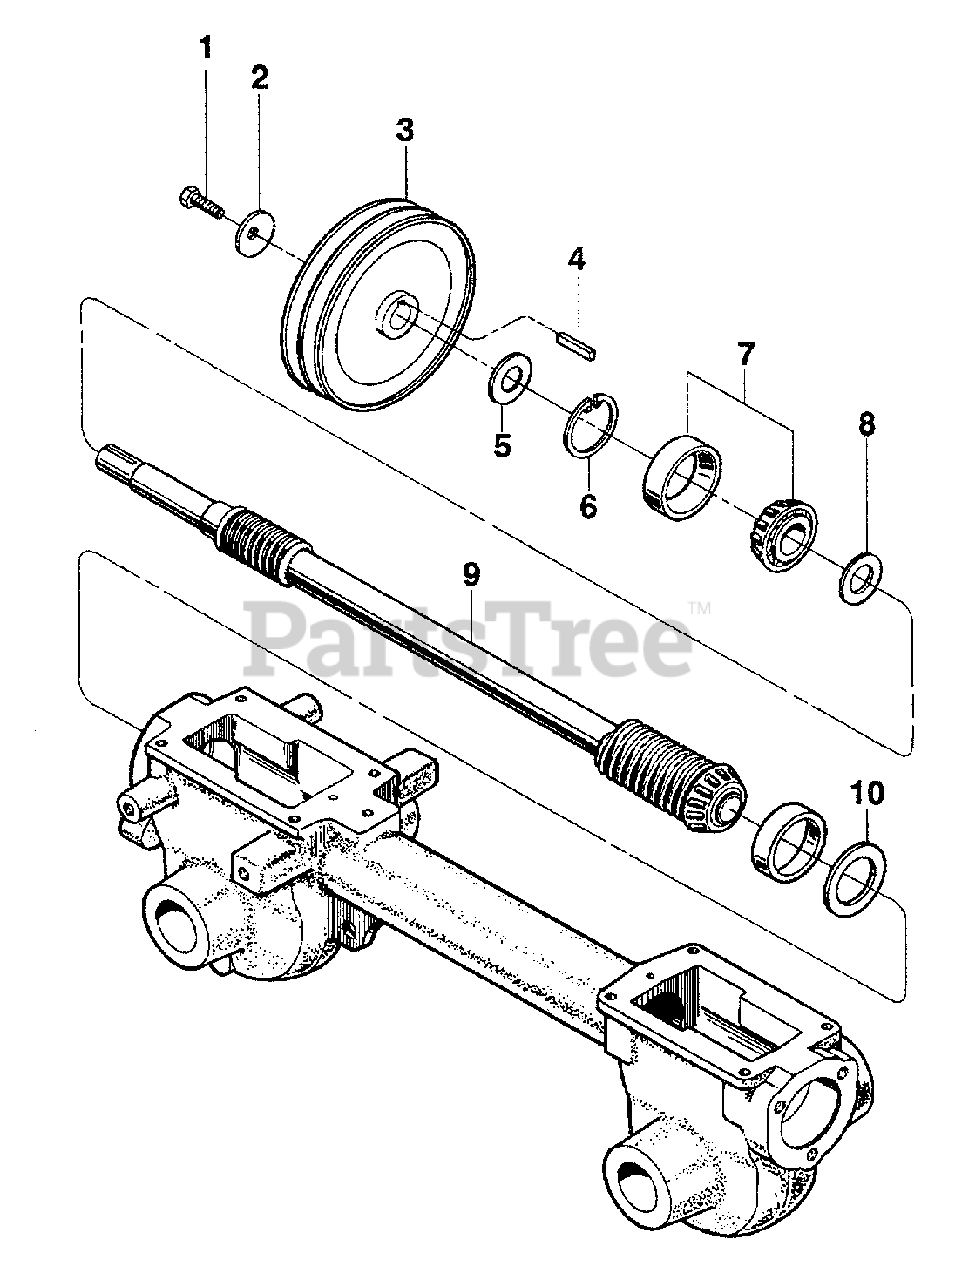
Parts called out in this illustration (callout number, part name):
1	Hex Screw, 5/16-24 x 3/4, Grade 5
2	Belleville Washer
3	Transmission Pulley
4	Key, Transmission Pulley, 3/16 x 1
5	Support Washer, Front
6	Snap Ring
7	Bearing, Tapered Roller (with race)
8	Support Washer, Rear
9	Drive Shaft Assy
10	Shim, Rear Bearing Cap, .010" thick
